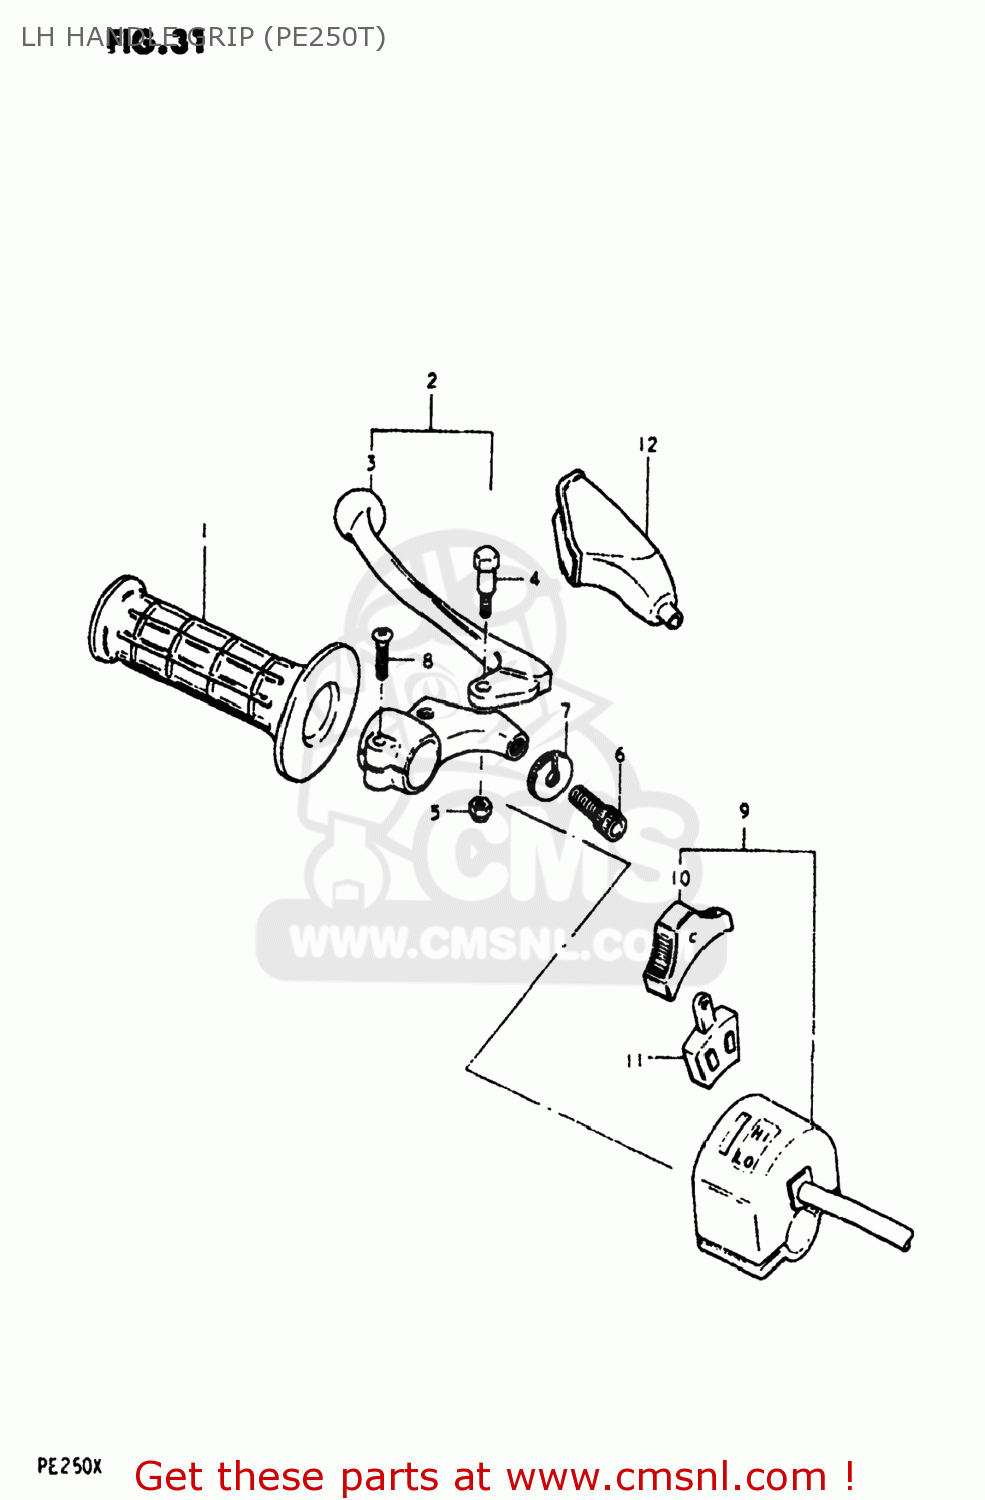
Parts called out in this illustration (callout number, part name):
1	GRIP,LEFT
2	LEVER ASSY,CLUTCH
3	LEVER,CLUTCH
4	BOLT,LEVER
5	NUT 6MM
6	ADJUSTER,CABLE
7	NUT,CABLE ADJUSTER
8	SCREW
9	SWITCH,DIMMER
10	KNOB,LIGHTING & DIMMER
11	BLOCK,LIGHTING/DIMMER
12	COVER,CLUTCH LEVER
